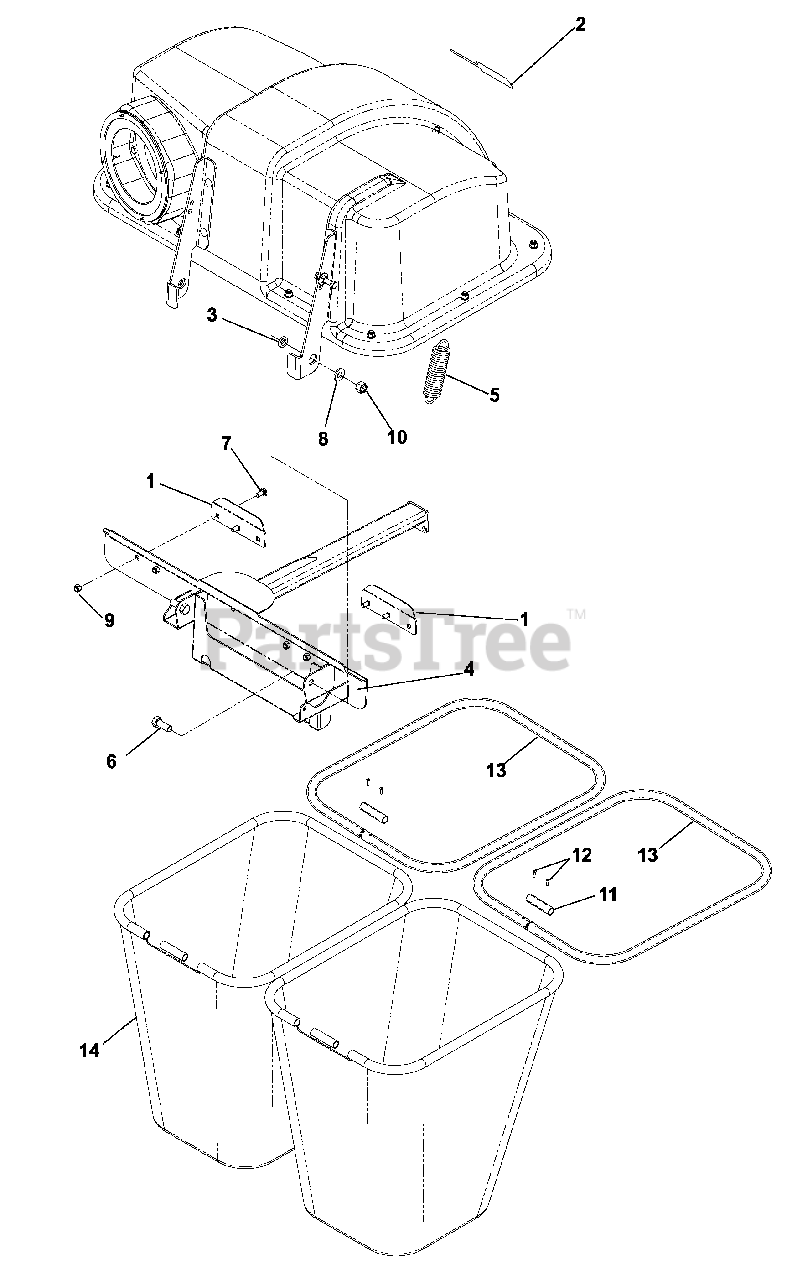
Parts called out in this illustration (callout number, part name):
1	BAG RETAINING CLIP
2	DECAL DIXON LOGO SM.
4	BAGGER MOUNT WLDT
6	HCS 1/2-13 X 1-1/4
7	BOLT 5/16C X 3/4" CARRIAGE
8	WASHER 1/2" FLAT
9	NUT 5/16 NYLOC
10	NUT 1/2-13 HEX NYLOC ZD
11	TUBE PLUG
12	6-20 X 1/2 PHIL PAN D/T
13	BAG TUBE SMALL
14	GRASS BAG
